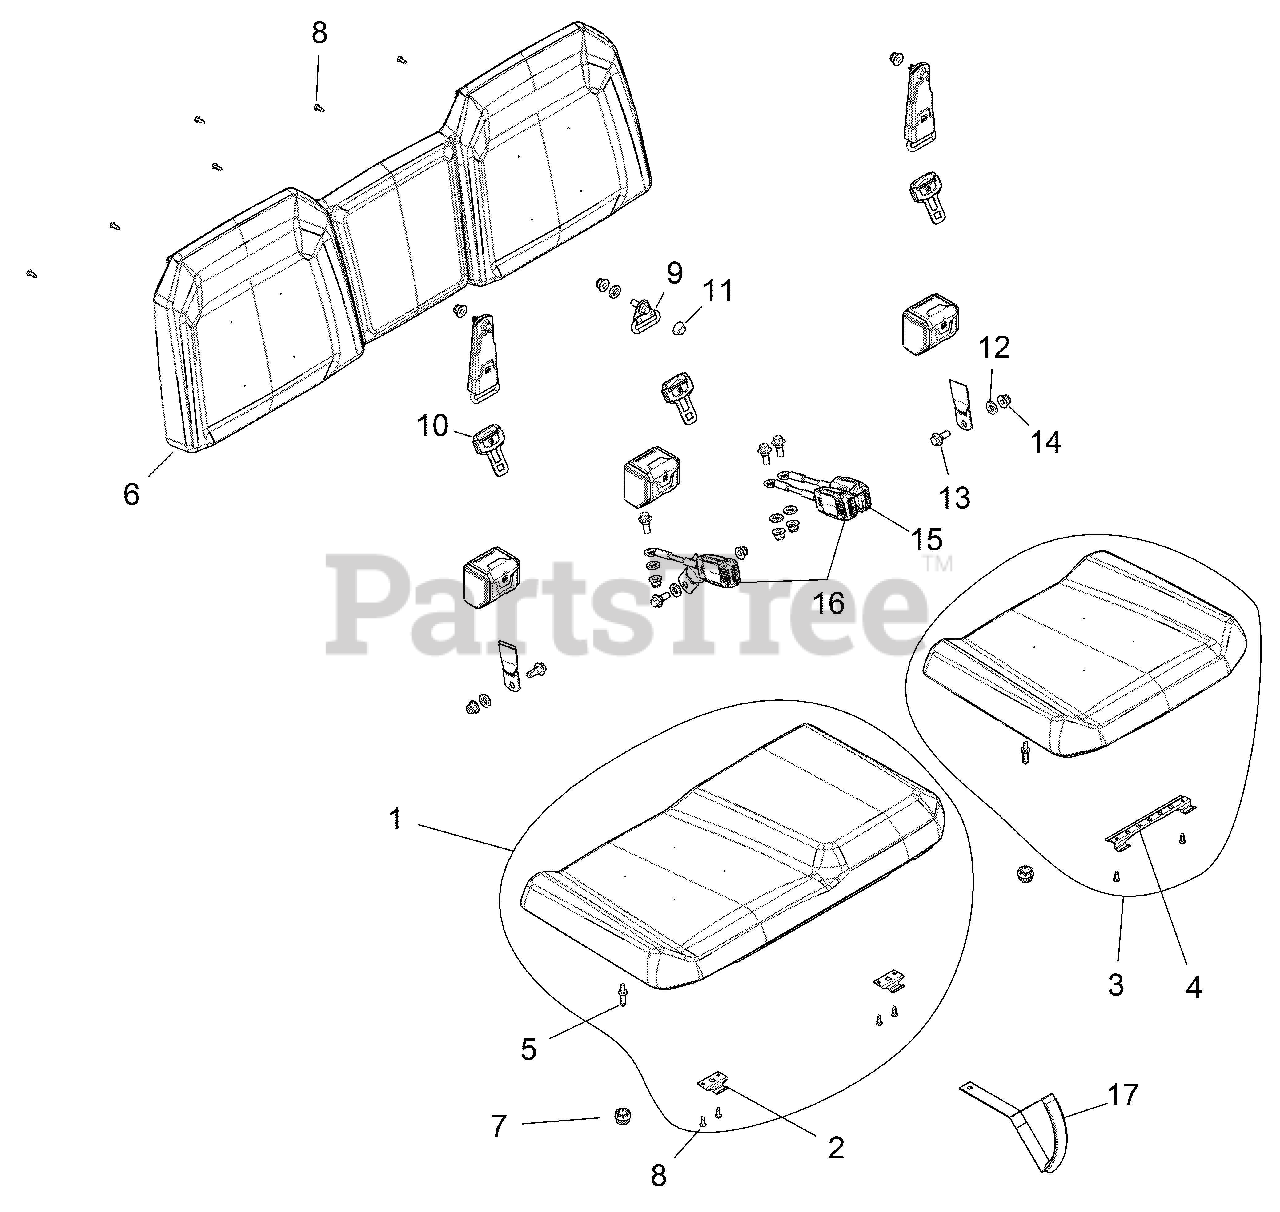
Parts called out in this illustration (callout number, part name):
1	ASM-SEAT,BTM,60,GRAVELY GRAY
2	BRKT-SEAT HINGE
3	ASM-SEAT,BTM,40,GRAVELY GRAY
4	BRKT-SEAT HINGE,DOUBLE
5	PIN-SEAT LATCH
6	ASM-SEAT,3PASS,BACK,GRVLY GRAY
8	SCR-TX TRUSS-#14X3/4,HI/LO ZBK
9	ASM-SEAT BELT,3PT,CENTER
10	ASM-SEAT BELT,3PT
11	CAP-BOLT HEAD
12	WASHER-SEATBELT,RUBBER
13	SCR-HXFLSH-M12X1.75-M14X9 ZOD
14	NUT-HXFL M12X1.75 NYLOC ZOD
15	BUCKLE-SEATBELT,9.6,DRIVER
16	BUCKLE-SEATBELT,9.6,PASSENGER
17	STRAP, SEAT, CENTER
